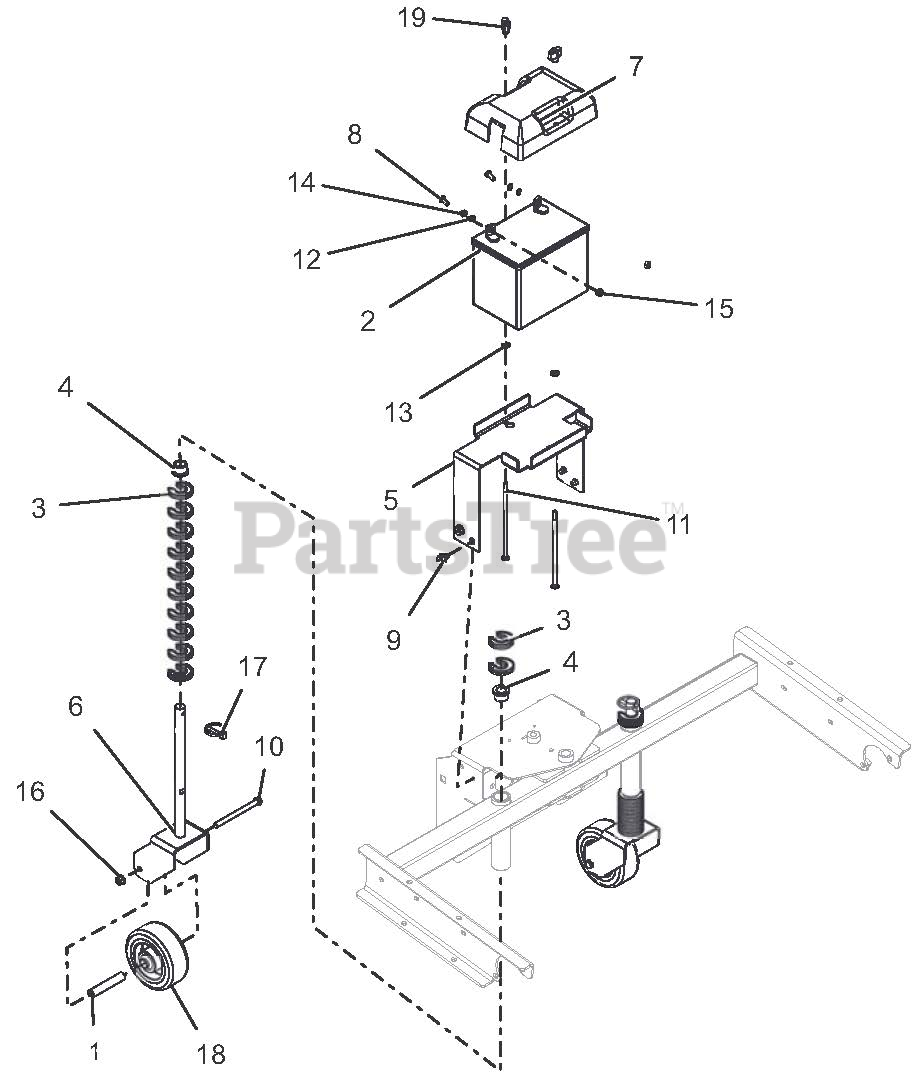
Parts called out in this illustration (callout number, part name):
1	SPCR, CASTER WHEEL
2	BATTERY, 300 CCA 10U1L
3	CLIP, HOC FIXED
4	BUSHING, FLANGE
5	TRAY, BATTERY - POWER BRUSH
6	FORK, CASTER
7	COVER, BATTERY
8	BLT-HEX .25-20X.75 GR5 YWZC
9	SCR-TAP .38-16X.50 HWH TR YWZ
10	BLT-HEX .38-16X4.50 GR5 YWZC
11	BLT -RDHDSQNK .25-20 X 7.00 G2 YZ
12	WSHR-LK .25X.062 REG YWZC
13	WSHR-FL-STL.281X.62X.065 YWZC
14	WASHER-FLAT-STL, .265 X .50 X .087
15	NUT-HEX .25-20 YWZC
16	NUT, LK-TOP-FLG .38-16 YWZC
17	PIN, 1/4 X 1 - 9/16 LYNCH
18	WHEEL, CASTER - 5" OD
19	KNOB, WING - .25-20 UNC
